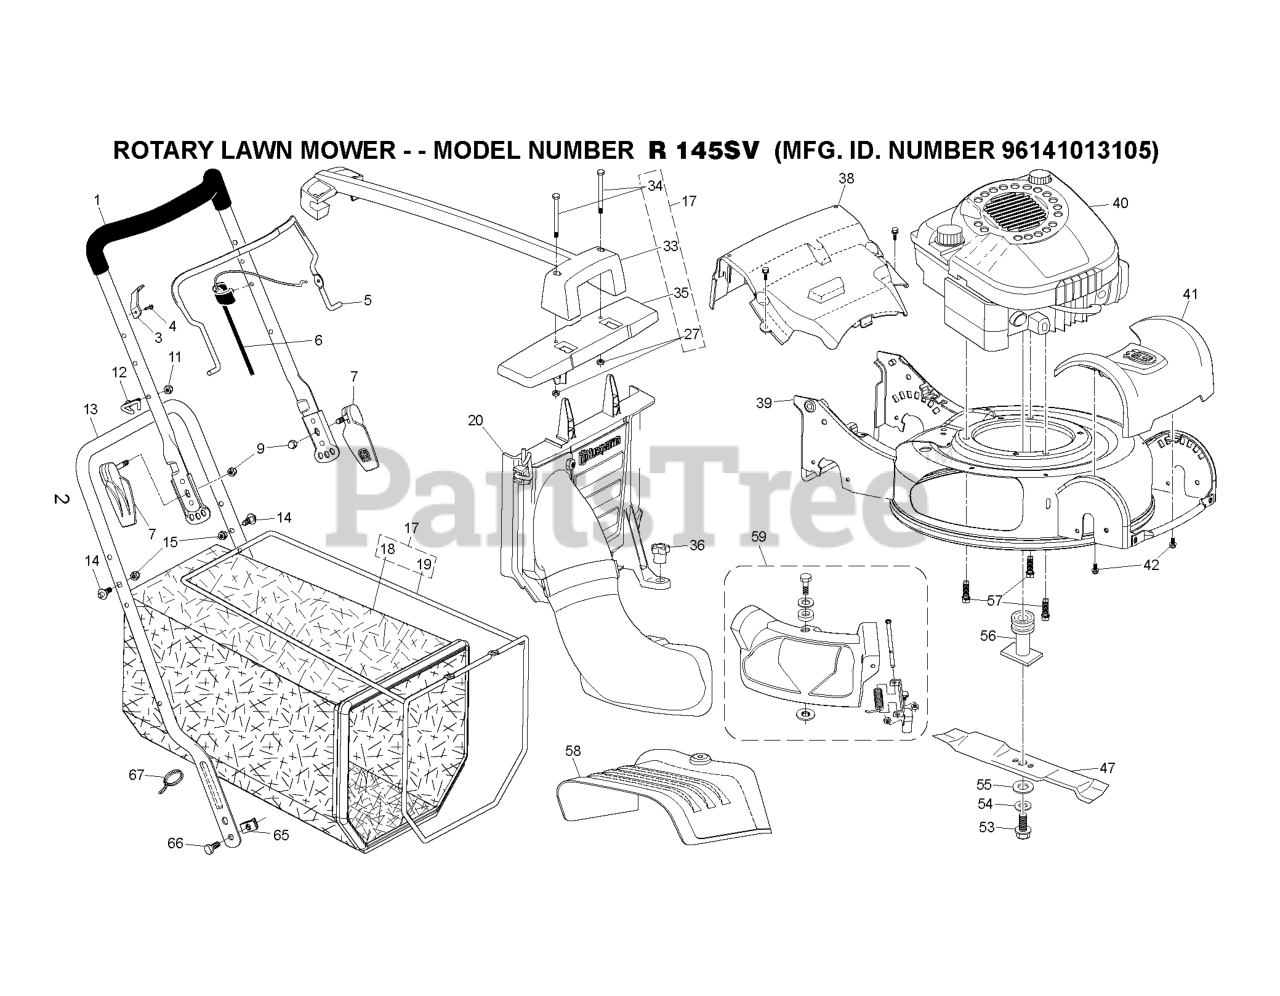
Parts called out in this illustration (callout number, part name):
1	HANDLE.ASM.UP.W/ADJ.BKT
3	BRACKET.UPSTOP.RT
5	BAIL.CONTROL.MZR.BS.ORANGE
6	CABLE.MZR.47.75.SNAP-IN.PU.L
7	QUICK.ASM.RELEASE.BLACK
9	Locknut, Hex 1/4-20
12	RB GUIDE.ROPE.STD.BLK.ZIN WSL
14	STUD.QUICK.ADJUST
15	NUT.LOCK.5/16-18
25	BRACKET
27	NUT
36	KNOB.MULCH.DOOR
42	SCREW.HWH.13-16-5.8.BZP
44	HINGE SCREW
46	SCREW.HEX.WSH
47	BLADE.SWEPT.WING.45CM.H.TREAT
53	BOLT.HD.HEAD.3/8-24X2.50 (2 2)
54	LOCKWASHER
55	WASHER,HARDEN
56	ADAPTER.BLADE
57	BOLT 3/8-16X1-1/8
67	TIE GUIDE
